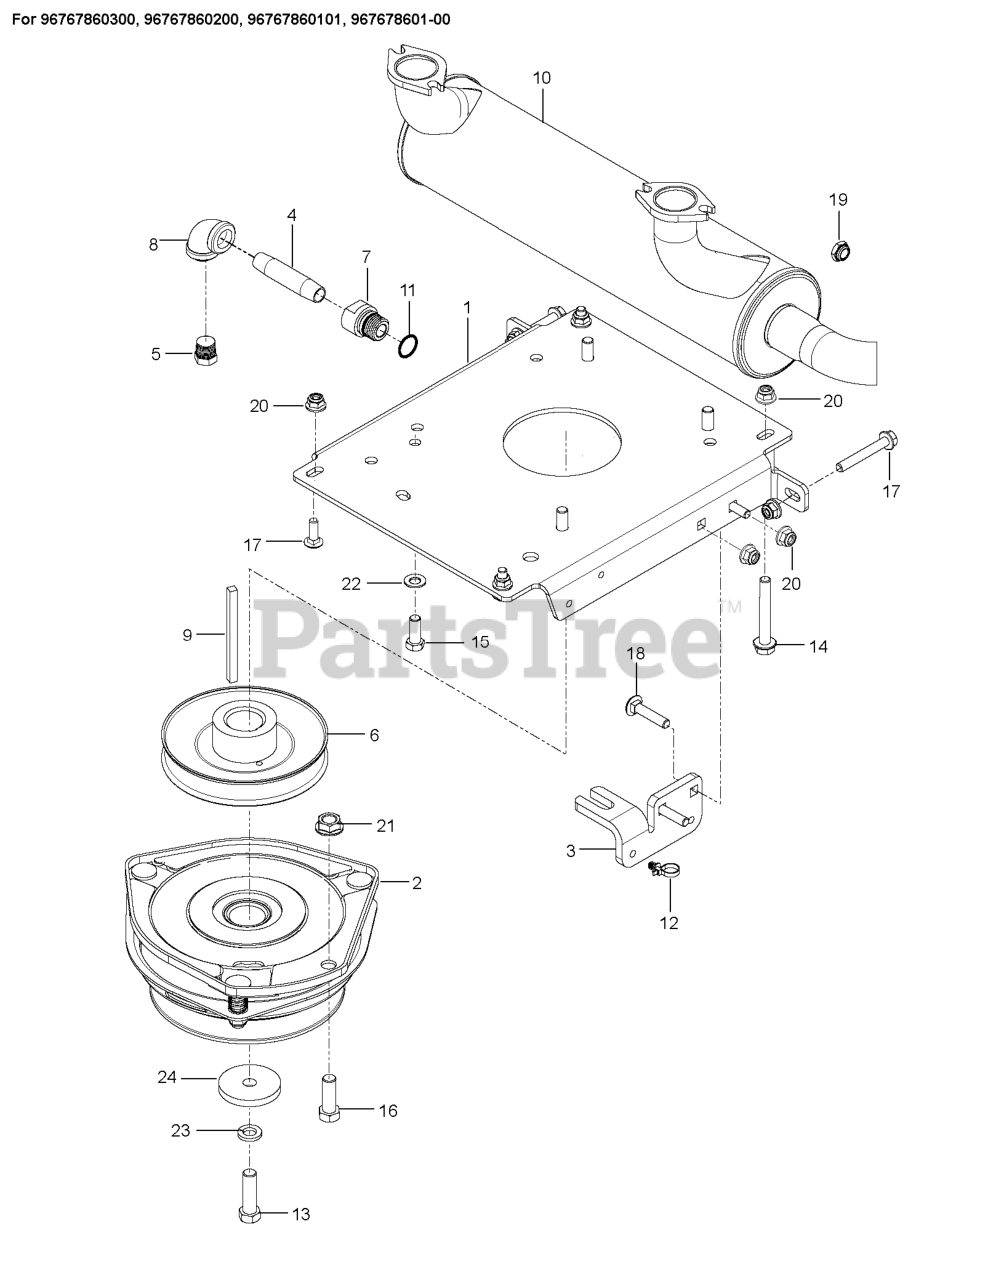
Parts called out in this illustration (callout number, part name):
1	PLATE.PNT.ENGINE.PZ/PZT.EDIP
2	CLUTCH, GT3.5
3	STOP, CLUTCH, OGURA
4	PIPE NIPPLE 3/8 X 3
5	PLUG, DRAIN 3/8 NPTF
6	PULLEY, ENGINE
7	ADAPTER, OIL DRAIN
8	90 DEG.ELBOW 3/8NPT
9	KEY, 1/4 SQ X 3.5
10	MUFFLER.KOH.EFI.824CC
12	TIE WRAP, 8-3/8", W/CLIP
13	CLUTCH BOLT7/16-20X1.5GR5.96HR
14	HHFS 5/16-18 X 2.25 GD 5
15	HCS 3/8-16X1.GRD.5.ZD
16	BOLT FIN HEX 7/16-14 X 1
17	RHSNB 5/16C X 1
18	RHSNB 5/16-18 X 1-1/2 GR 5 ZD
19	JAM NUT 1/4C (2 2 PW01)
20	5/16-18 NYLOC FLANGE NUT
21	NUT 7/16C WHIZ
22	WASHER, 3/8 DISC SPRING SPEC
23	WASHER 7/16 LOCK
24	BLADE WASHER
